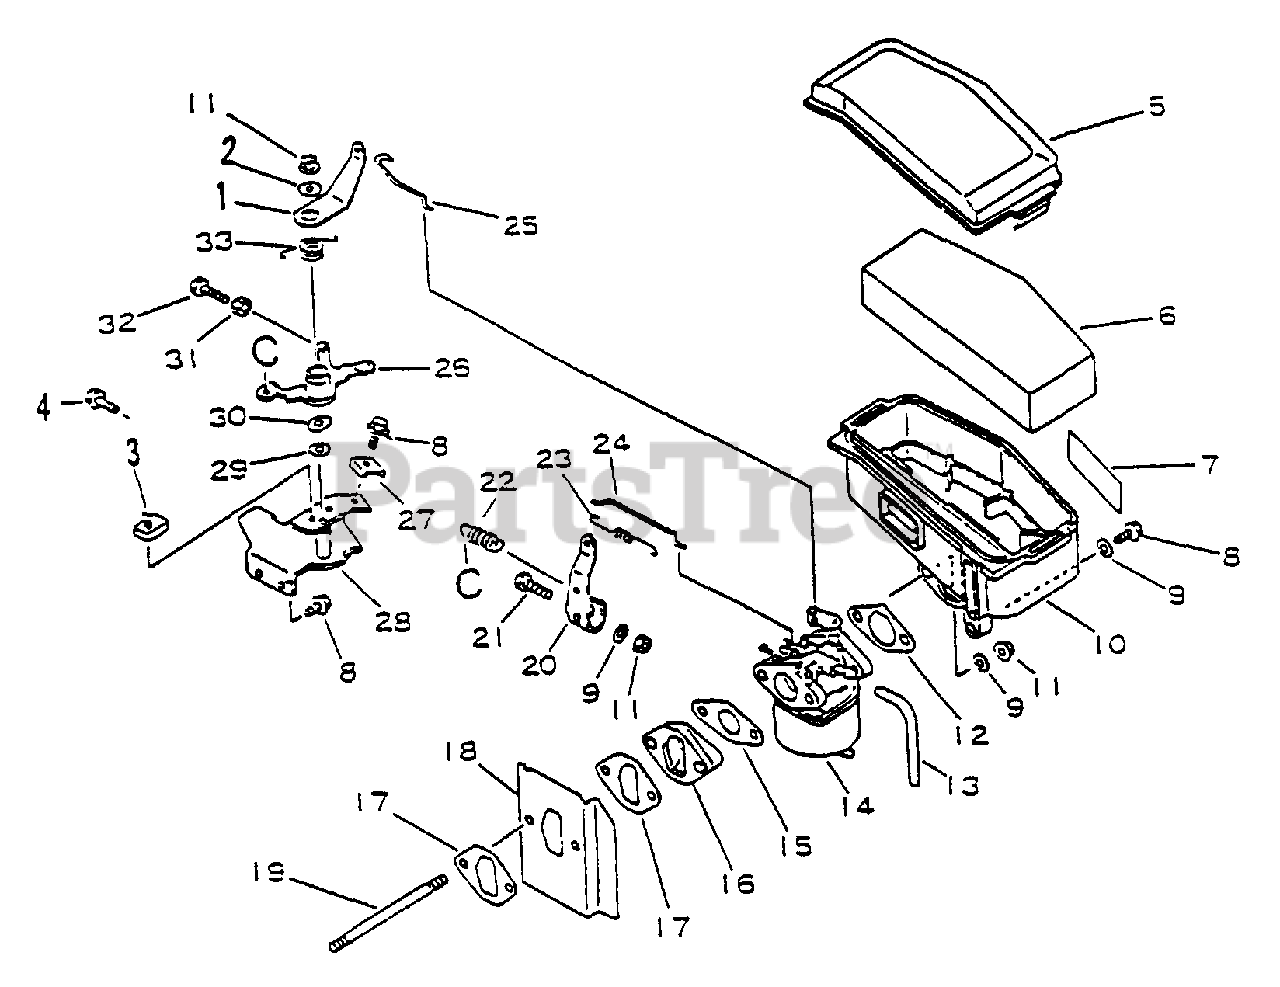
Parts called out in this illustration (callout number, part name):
1	CONNECTOR, CHOKE ROD
2	WASHER - 6
3	SWITCH, IGNITION
4	BOLT - 8X14
5	COVER, AIR FILTER
6	FILTER, AIR
7	LABEL - CAUTION
8	BOLT - 6X16
9	WASHER - 6
10	CASE, AIR FILTER
11	NUT - 6 -- FLANGE
13	PIPE - 3X5X100 -- BLACK
14	CARBURETOR
15	GASKET, INTAKE
16	INSULATOR, INTAKE
17	GASKET, INTAKE
18	SHIELD, INTAKE
19	STUD
20	ARM, THROTTLE
21	BOLT - 6X25
23	SPRING, TRIGGER
24	ROD, THROTTLE
25	ROD, CHOKE
26	TRIGGER, THROTTLE
27	BRACKET
28	BRACKET, THROTTLE
29	WASHER - 8
30	WASHER
32	BOLT - 4X10
33	SPRING, CHOKE
